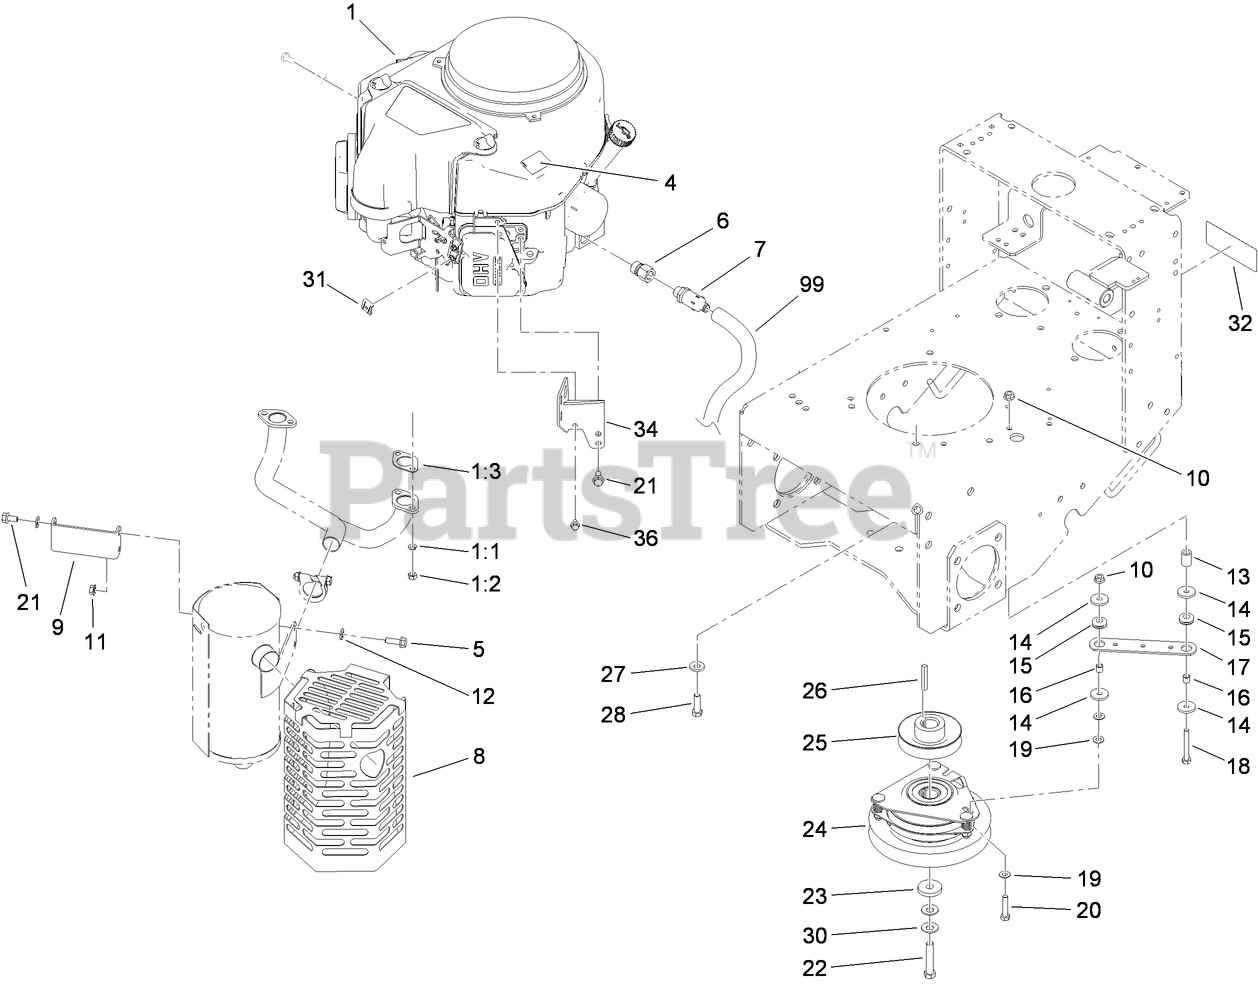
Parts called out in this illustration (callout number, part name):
1:1	WASHER-LOCK
1:3	GASKET-EXHAUST
4	DECAL-WARNING
5	SCREW-HHF
6	Adapter
7	VALVE-DRAIN, OIL
8	SHIELD-MUFFLER
9	BRACKET-SHIELD, MUFFLER
10	NUT-HF
11	NUT-HF, LOCK
12	WASHER-SPRING
13	TUBE-RETAINER
14	WASHER
15	GROMMET
16	SPACER
17	STRAP-CLUTCH, BRAKE
18	SCREW-HH
19	WASHER-PLAIN
20	SCREW-HH
21	SCREW-HHF
22	SCREW-HH
23	WASHER
24	CLUTCH / BRAKE ASM
25	Pulley
26	KEY-SQUARE
27	WASHER-BELLEVILLE
28	SCREW-HH
30	WASHER-SPRING
31	CLAMP-CABLE
32	DECAL-CAUTION
34	BRACKET-MUFFLER
36	SCREW-HHF
99	HOSE-DRAIN, OIL
